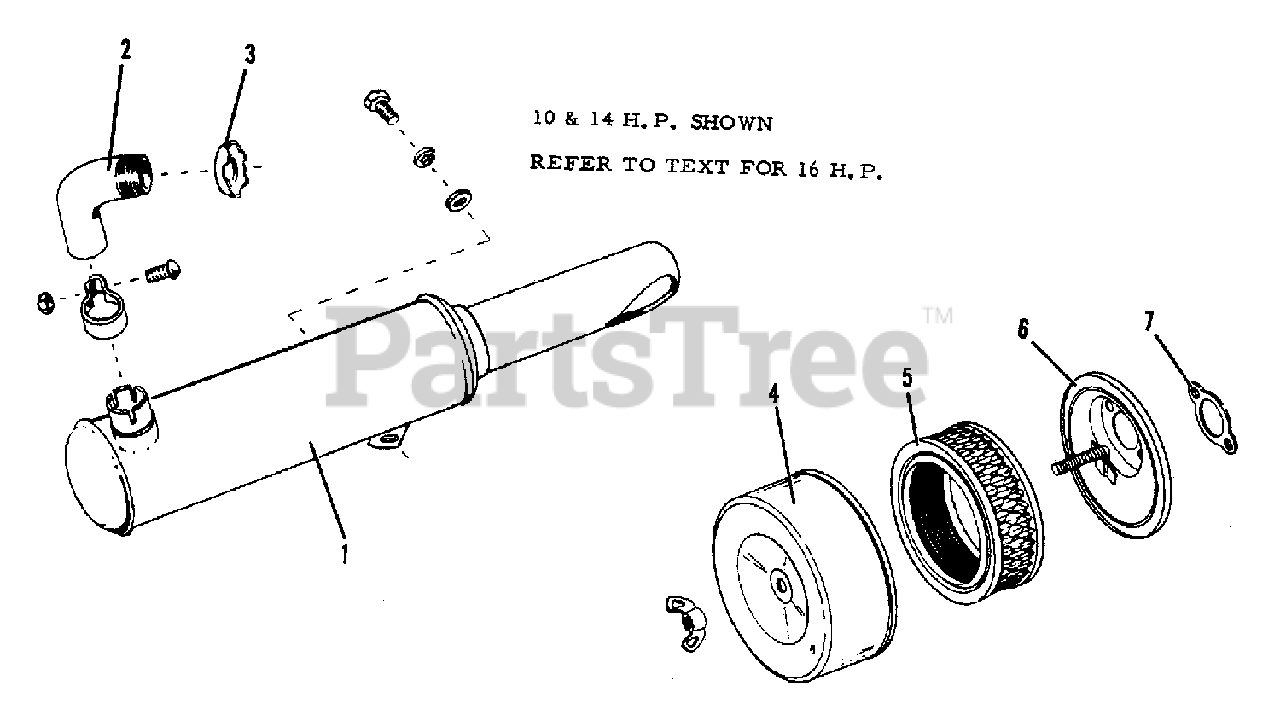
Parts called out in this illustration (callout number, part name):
1	MUFFLER ASSEMBLY, 10 H.P. (Includes BRACKET)
1	MUFFLER ASSEMBLY, 16 H.P. (Includes BRACKET)
1	CAPSCREW, 7.16NC x 7/8
1	LOCKWASHER, 7/16
1	NUT, 7/16NC, Lock
2	ELBOW, Exhaust (10 H.P.)
2	PIPE ASSEMBLY, Exhaust (16 H.P. )
3	NUT, Lock (10 H.P.)
3	NUT, Lock (16 H.P.)
4	COVER, Air Cleaner (10 H.P.)
4	COVER, Air Cleaner (16 H.P.)
5	ELEMENT, Filter (10 H.P.)
5	ELEMENT, Filter (16 H.P.)
6	BASE, Air Cleaner (10 H.P.)
6	BASE, Air Cleaner (16 H.P.)
6	NUT, Wing
7	GASKET, Air Cleaner
